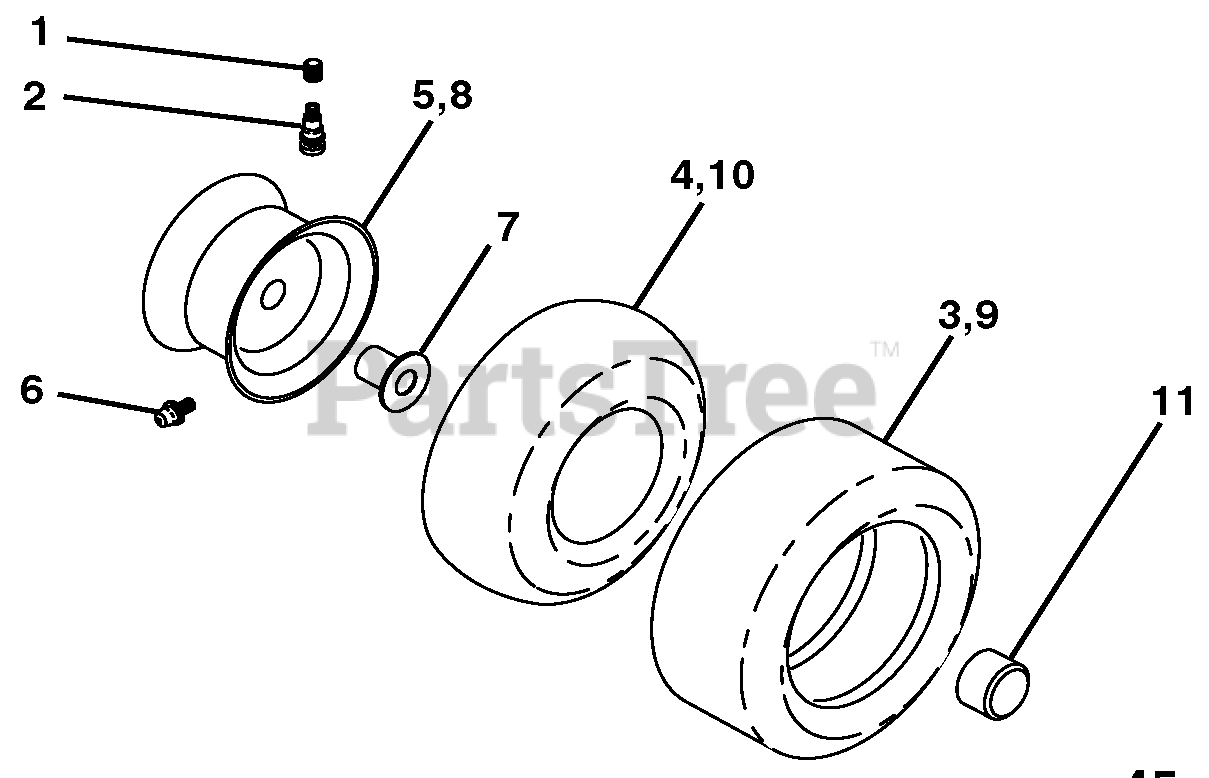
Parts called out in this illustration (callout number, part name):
1	Cap Valve Tire
2	Stem Valve
3	Tire Front
4	Tube Front
5	Rim Asm 8" front
6	Fitting Grease
7	Bearing Flange
8	Rim Asm 12" rear
9	Tire R 23 x 8.5-12 C Service
10	Tube Rear
11	Cap Axle Blk 1 50 X 1 00
11	Sealant, Tire (1 Doz. Tube)
